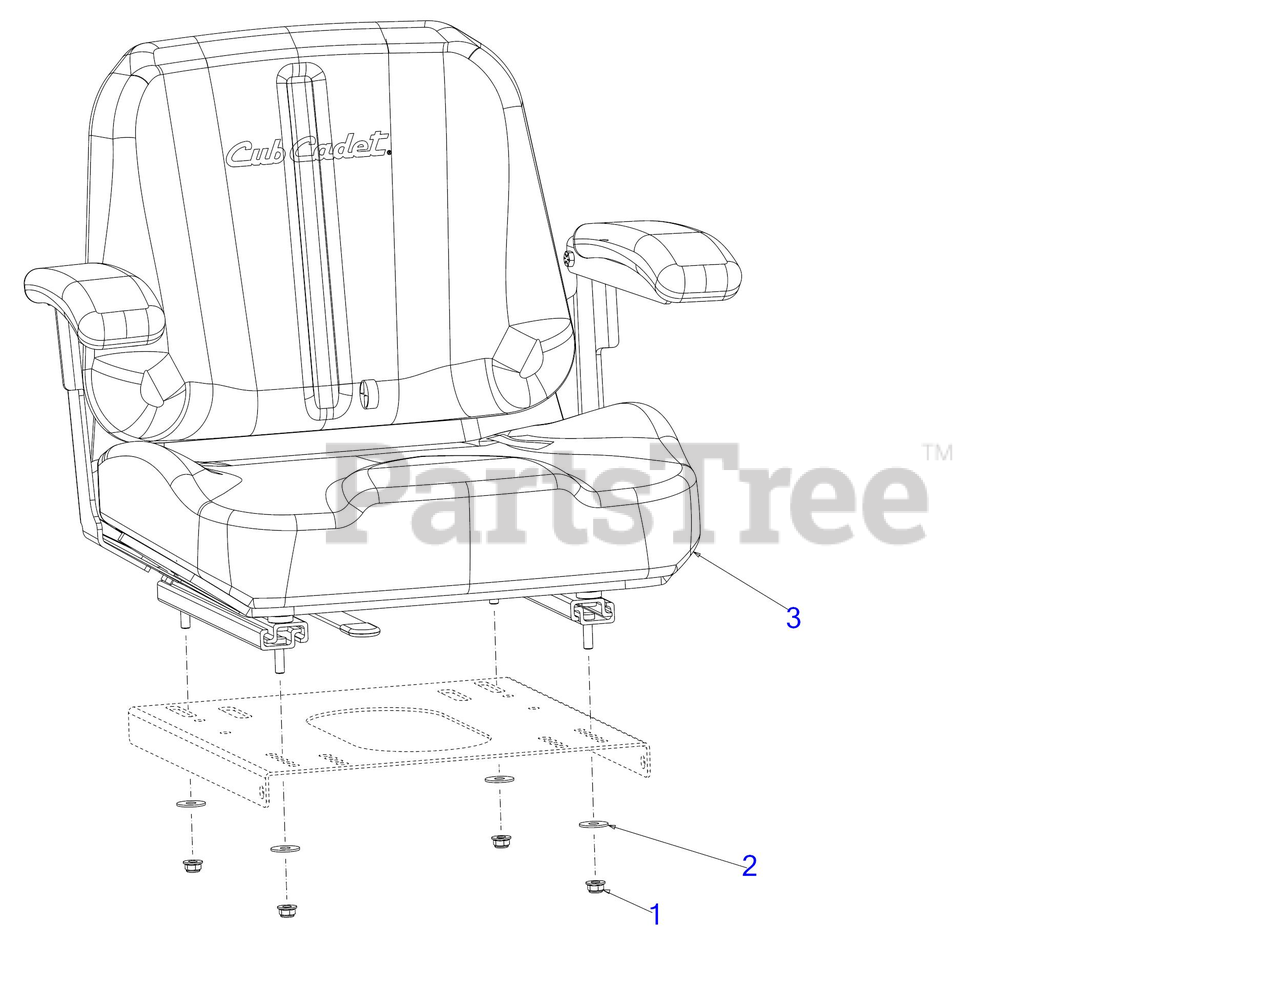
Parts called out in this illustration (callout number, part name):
1	FLANGE LOCK NUT 5/16-18
2	FLAT WASHER 344X1.00
3	SEAT-18.5 W/SLIDES/ARM
